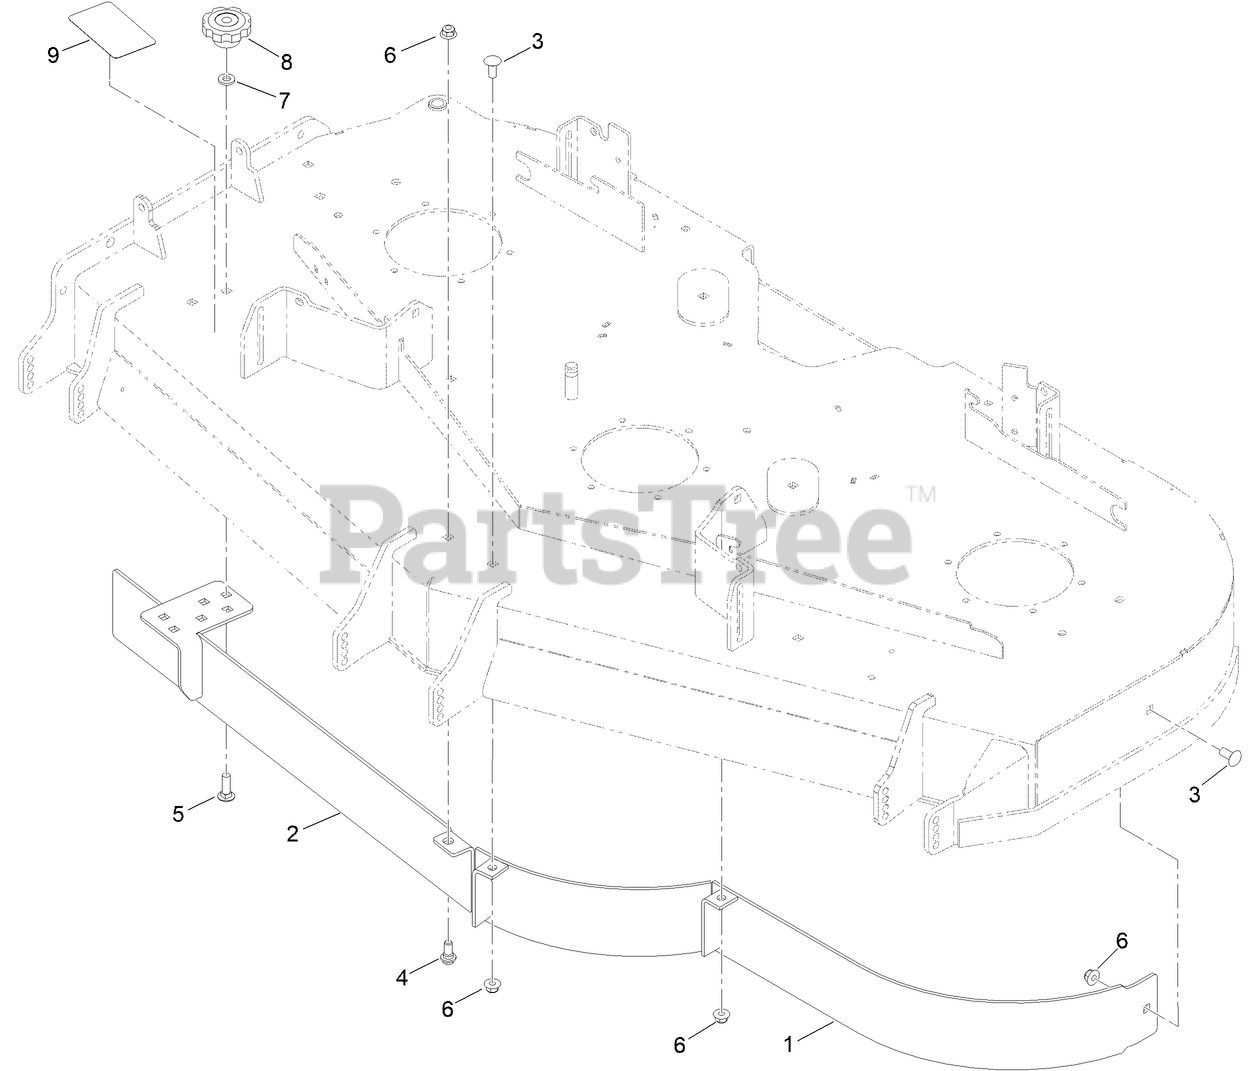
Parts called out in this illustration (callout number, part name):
2	BAFFLE-TURBO FORCE
3	SCREW-CARR
4	BOLT-SHOULDER
5	BOLT-CARR
6	NUT-HF, NI
7	WASHER-HARDENED
9	DECAL-ADJUSTABLE BAFFLE
